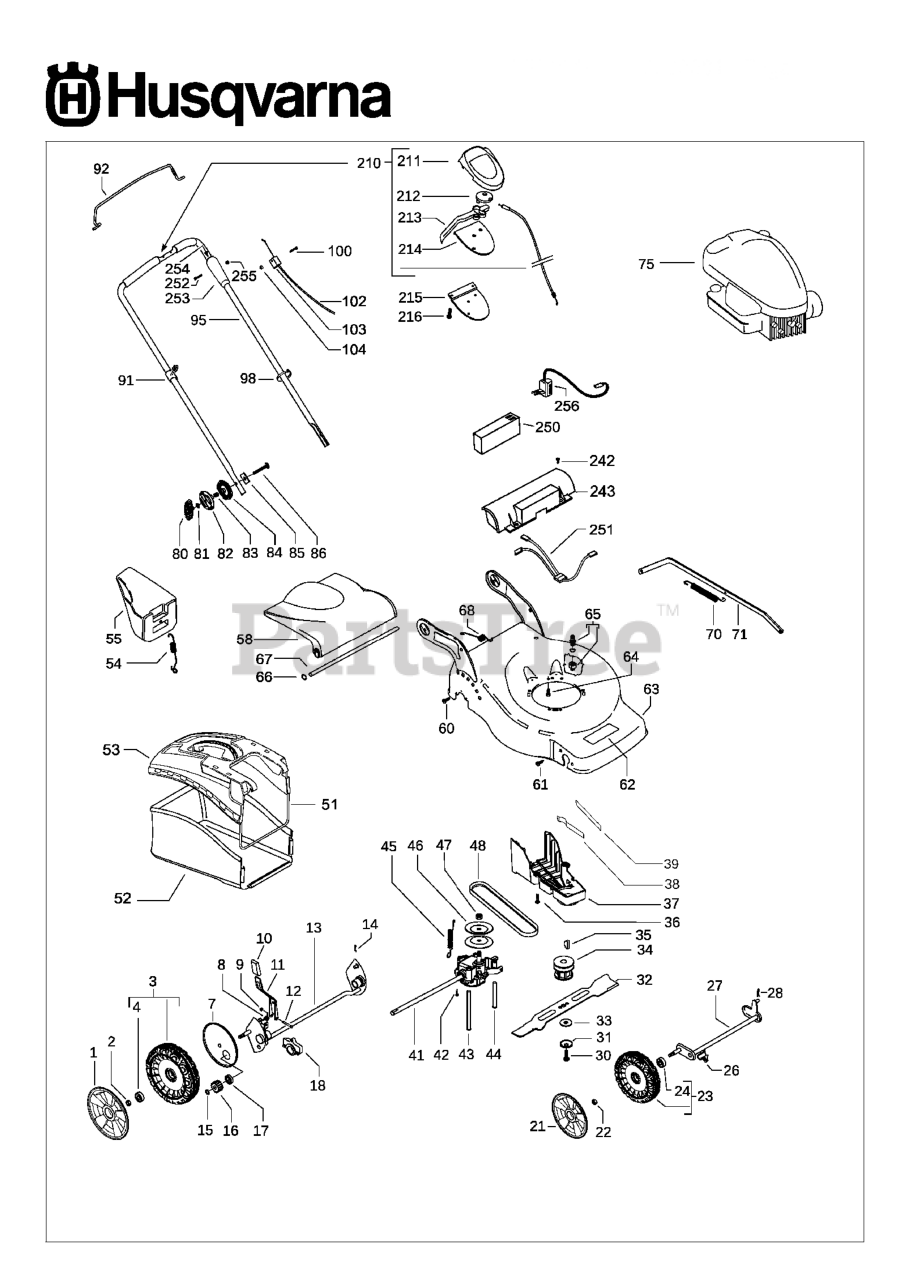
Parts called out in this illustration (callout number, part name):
32	MOWER BLADE COMBI
34	BLADE SUPPORT
95	HANDLE ASSY
102	BRAKE WIRE
211	COVER, DRIVE CONTROL, TOP
212	PULLEY.CAM.DRIVE.CONTROL.HV
212	PULLEY.CAM.DRIVE.CONTROL.EZ
213	LEVER, DRIVE CONTROL
214	COVER, DRIVE CONTROL BOTTOM
215	BRACKET, DRIVE CONTROL
216	SCREW, PHILLIPS HEAD 10 X 5/8
252	SCREW ITXSCM M6X40/25 T27 12.
253	RP CONTROLSH.BUTTON.START.22"
254	BUTTON.PUSHBUTTON.ES
255	LOCKNUT M6
256	CHARGER.BATTERY.CE
